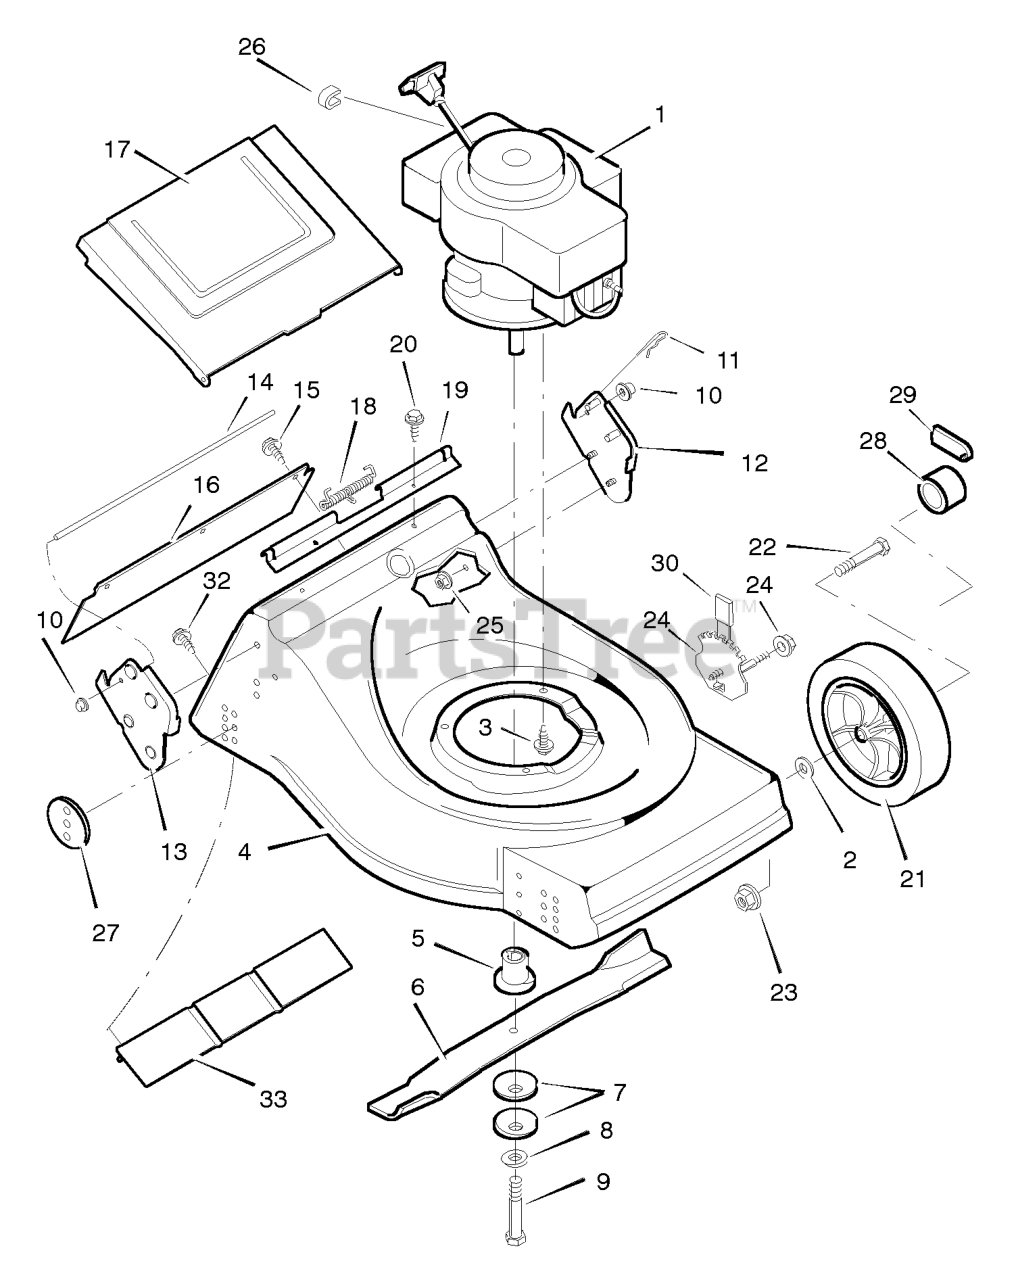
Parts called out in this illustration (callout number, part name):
1	Engine *
3	Bolt, Engine
4	Housing
5	Adapter, Blade
7	Washer, Belleville
9	Bolt, Hex
10	Push- On Cap
11	Pin, Hair
12	Bracket, Left Handle
13	Bracket, Right Handle
14	Rod, Door Pivot
16	Deflector, Rear
17	Door, Rear
18	Spring, Torsion
19	Spacer, Door
21	Wheel and Tire *
22	Bolt, Axle
23	Nut, Flange
24	Adjuster, Height
25	Nut, Flange
26	Stop, Rope
28	Hub Cap
29	Hub Cap
33	Baffle, Rear
